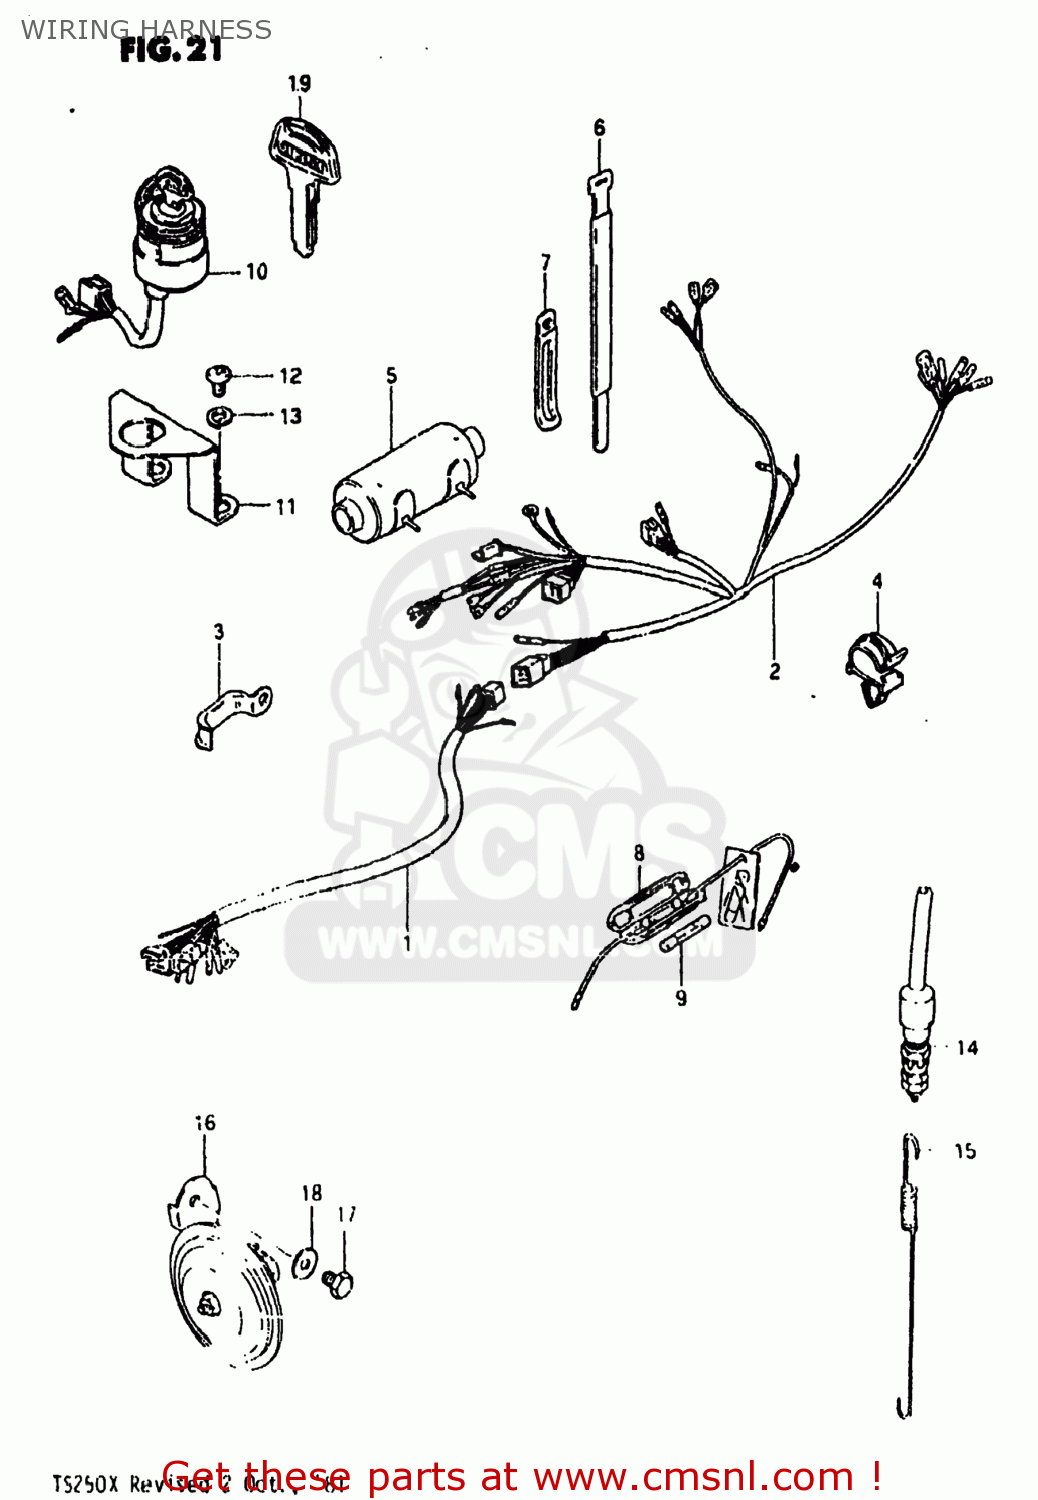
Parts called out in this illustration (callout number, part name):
1	HARNESS,WIRING
2	HARNESS,WIRING NO.2
3	CLAMP
4	CLAMP
5	BOOT,WIRING HARNESS
6	CLAMP
7	CLAMP L:35
8	BOX ASSEMBLY,FUSE
9	FUSE(15A)
10	SWITCH ASSEMBLY,IGNITION
11	BRACKET,IGNITION SWITCH
12	SCREW
13	LOCK WASHER
14	SWITCH ASSEMBLY,STOP LAMP
15	SPRING
16	HORN ASSEMBLY
17	BOLT
18	WASHER
19	KEY,BLANK
